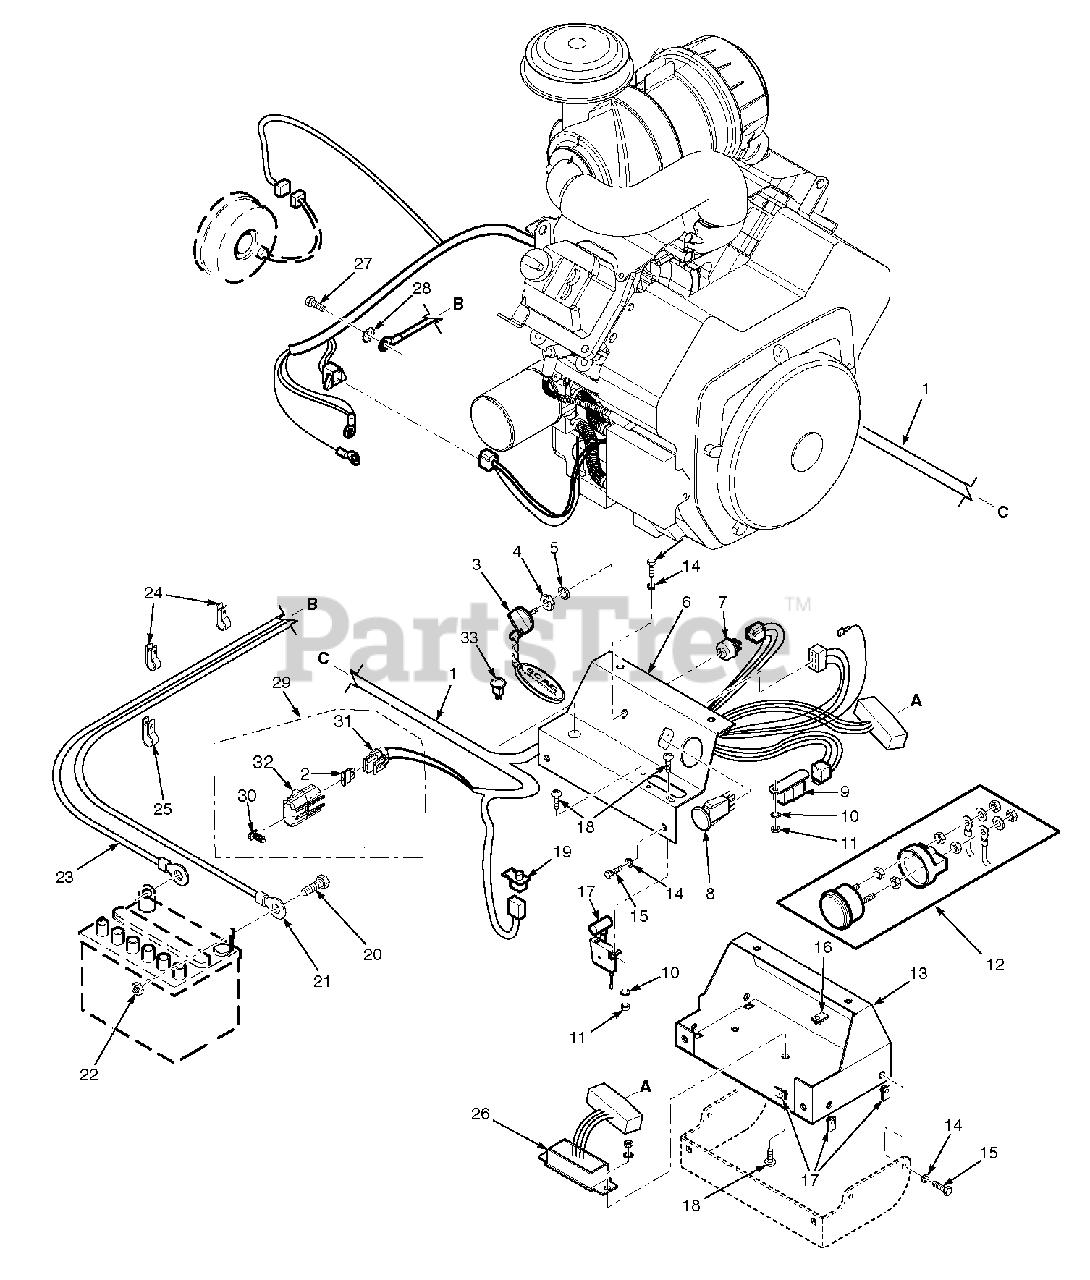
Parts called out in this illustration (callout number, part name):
1	Wire Harness, STT 26CH-EFI Air-Cooled
2	Fuse, 20 AMP
3	Key, Ignition
3	Key Assembly w/Fob
4	Nut, Hex 5/8-32
5	Lockwasher, 5/8" Internal
6	Instrument Panel, Top w/Decals
7	Key Switch
8	Switch, PTO
9	Relay
10	Lockwasher, #10 External Tooth
11	Nut, Hex #10-32
12	Volt Meter
13	Base, Instrument Panel
14	Lockwasher, 1/4"
15	Bolt, Hex Head 1/4-20 x 3/4"
16	U-Nut, 1/4-20
17	Throttle And Choke Controls (Kohler)
18	Screw, Phillips Washer Head #10-32 x 1/2"
19	Switch, Interlock-Seat
20	Bolt, Hex Head 1/4-20 x 1/2"
21	Cable, Battery - Red
22	Nut, Hex 1/4-20
23	Cable, Battery - Black
24	Clamp, Cable 1/2" ID.
25	Clamp, Cable 3/4" ID.
26	Electronic Module
27	Bolt, Hex Head M8-1.25 x 20mm
28	Lockwasher, 5/16" External Tooth
29	Double Fuse Assembly, Sealed
30	Clip, Wire
31	Fuse Holder
32	Cover, Sealed Single
33	Indicator Light
